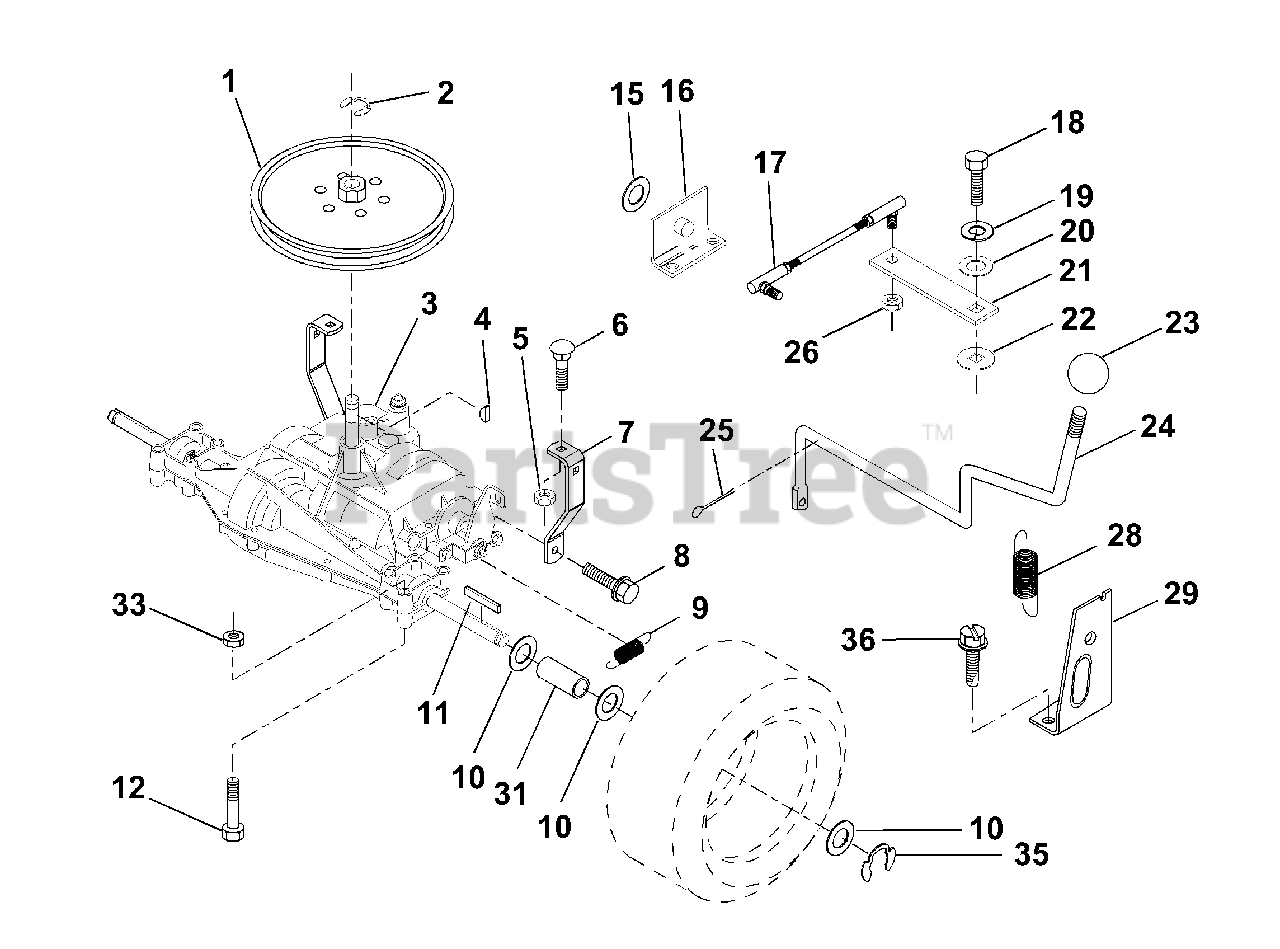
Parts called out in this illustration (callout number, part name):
2	Ring, Retainer
4	Key, Woodruff #9
5	Nut, Crownlock 5/16-18
6	Bolt, Carriage 5/16-18 UNC x 3/4
7	Strap, Torque
8	Screw 5/16-18 x 3/4
9	Spring, Brake
10	Washer 25/32 x 1-1/4 x 16 Ga.
11	Key, Square
12	Bolt, Fin Hex 3/8-16 Unc x 2-3/4
15	Washer 17/32 x 1 x 16 Ga.
16	Support Handle Shift LH
17	Link, Shift
18	Bolt, Fin Hex 1/4-28 UNF x 3/4 Gr. 8
19	Washer, Lock 1/4
20	Washer 9/32 x 3/4 x 10 Ga.
21	Arm, Shift
22	Washer, Shift Plate
23	Knob, Rd 1/2-13
25	Pin, Cotter 1/8 x 1
26	Locknut 5/16-24 UNF
28	Extension, Spring
29	Support Handle Shift RH
31	Spacer Axle
33	Nut Crownlock 3/8-16 Unc
36	Screw
